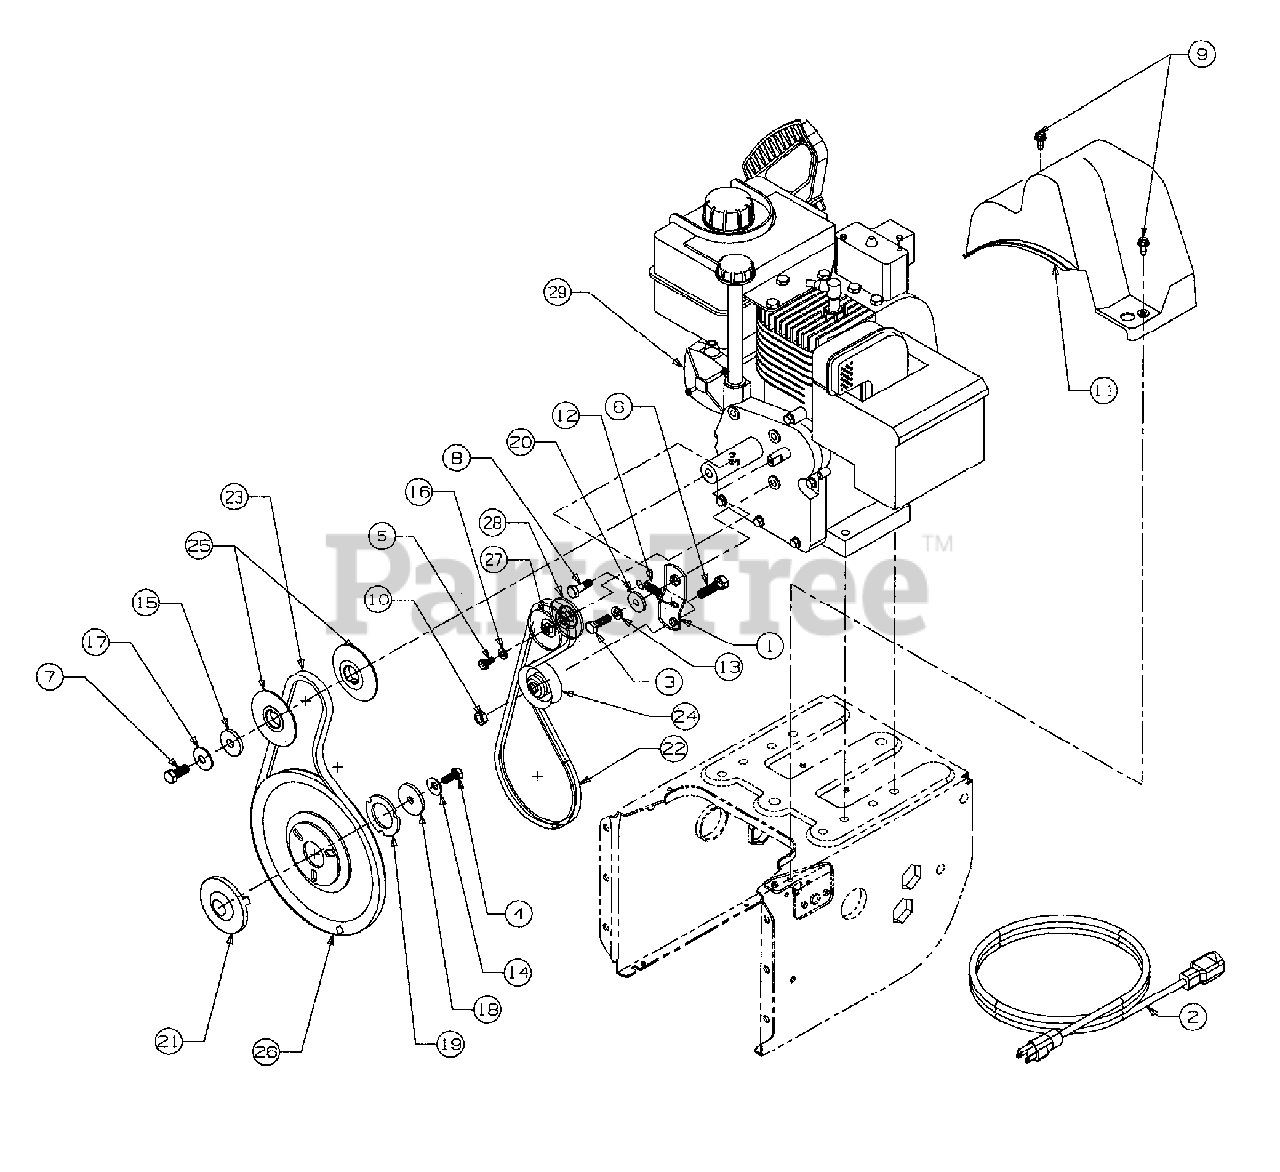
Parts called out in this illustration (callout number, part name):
3	Screw - Hex
4	Screw - Hex
5	Screw - Hex
6	Screw - Hex
7	Screw - Hex
8	Screw - Hex
9	Screw - Hex
10	Nut - Hex
11	Cover - Belt
12	Spring
13	Washer - Lock
14	Washer - Bell
15	Washer - Flat
16	Washer - Lock
17	Washer - Lock
18	Washer - Flat
19	Washer
20	Spacer
21	Adapter - Pulley
22	V - Belt
23	V - Belt
24	Idler - Flat
25	Pulley - Half
26	Pulley
27	Pulley - Half
28	Pulley - Half
29	Electric Start Kit
